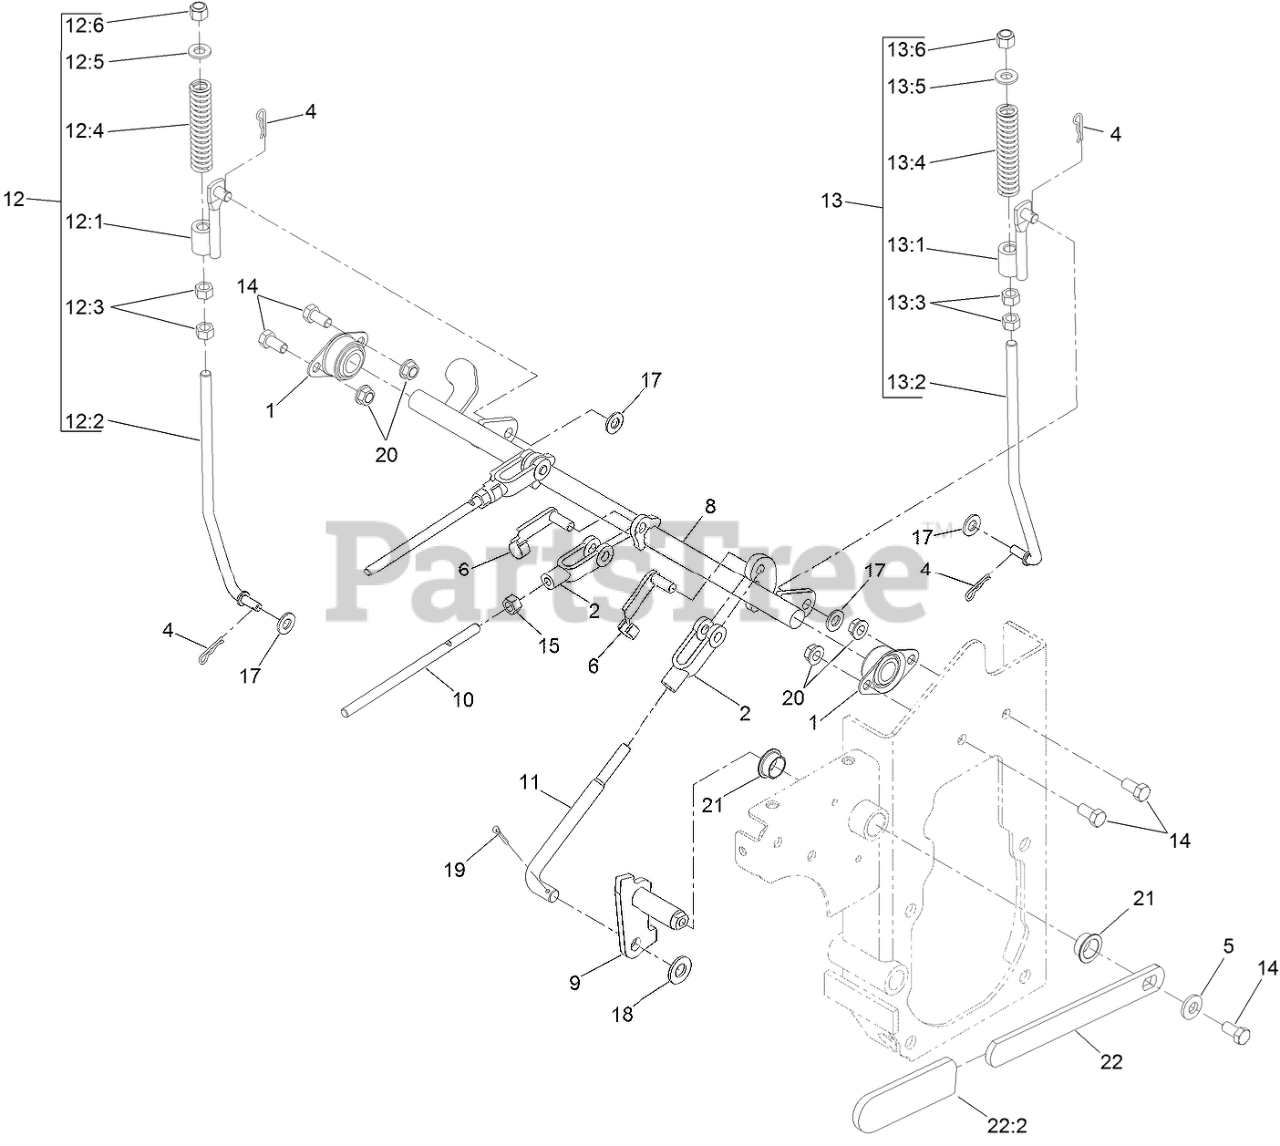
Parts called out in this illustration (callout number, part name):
1	BEARING-FLANGE, SIDE
2	YOKE-LINKAGE, BRAKE
4	PIN-COTTER
5	WASHER-BELLEVILLE
6	PIN-SPRING, CLEVIS
8	SHAFT-BRAKE
9	PIVOT-BRAKE
10	ROD-LINKAGE, BRAKE
11	ROD-LINKAGE, BRAKE
12	RH BRAKE LINKAGE ASM
12:1	BRAKE LINKAGE ASM
12:2	LINK-BRAKE, RH
12:3	NUT-HEX
12:4	SPRING-COMPRESSION
12:5	WASHER-FLAT
12:6	NUT-LOCK
13	LH BRAKE LINKAGE ASM
13:1	BRAKE LINKAGE ASM
13:2	LINK-BRAKE, LH
13:3	NUT-HEX
13:4	SPRING-COMPRESSION
13:5	WASHER-FLAT
13:6	NUT-LOCK
14	SCREW-HH
15	NUT-HEX
17	WASHER-FLAT
18	WASHER-FLAT
19	PIN-COTTER
20	NUT-HHF, WHIZ
21	BUSHING-BRONZE
22	PARK BRAKE HANDLE ASM
22:2	GRIP-LEVER
